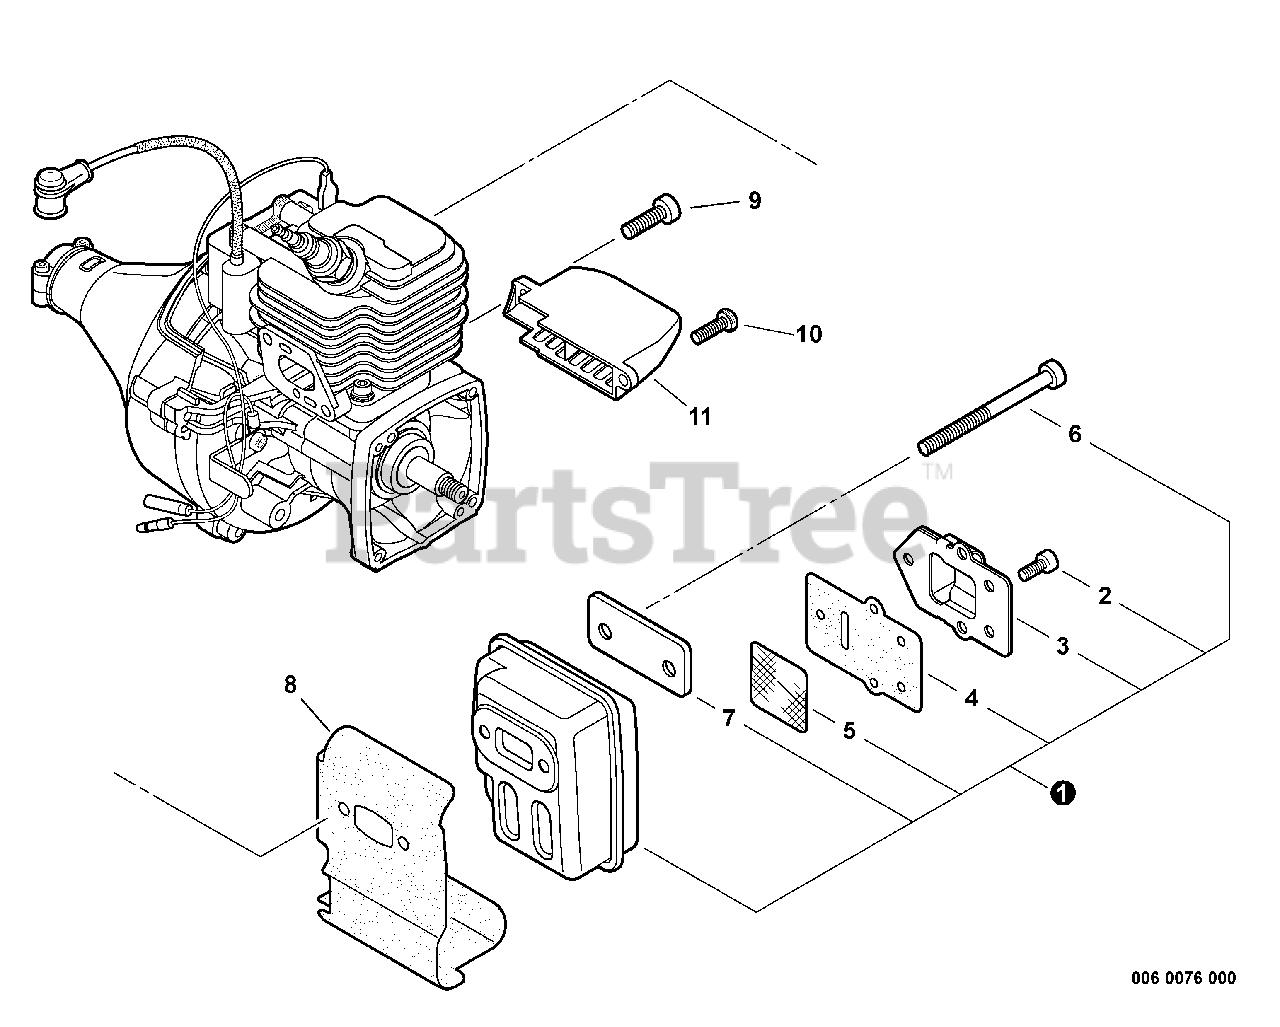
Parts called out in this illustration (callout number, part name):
1	MUFFLER ASSY
2	BOLT, TORX 4×8
3	GUIDE, EXHAUST
4	GASKET, EXHAUST
5	SCREEN, SPARK ARRESTER
6	BOLT, TORX 5×55
7	PLATE, EYE
8	HEAT SHIELD, EXHAUST
9	BOLT, TORX 5×16
10	BOLT, TORX 5×16
11	COVER, MUFFLER
